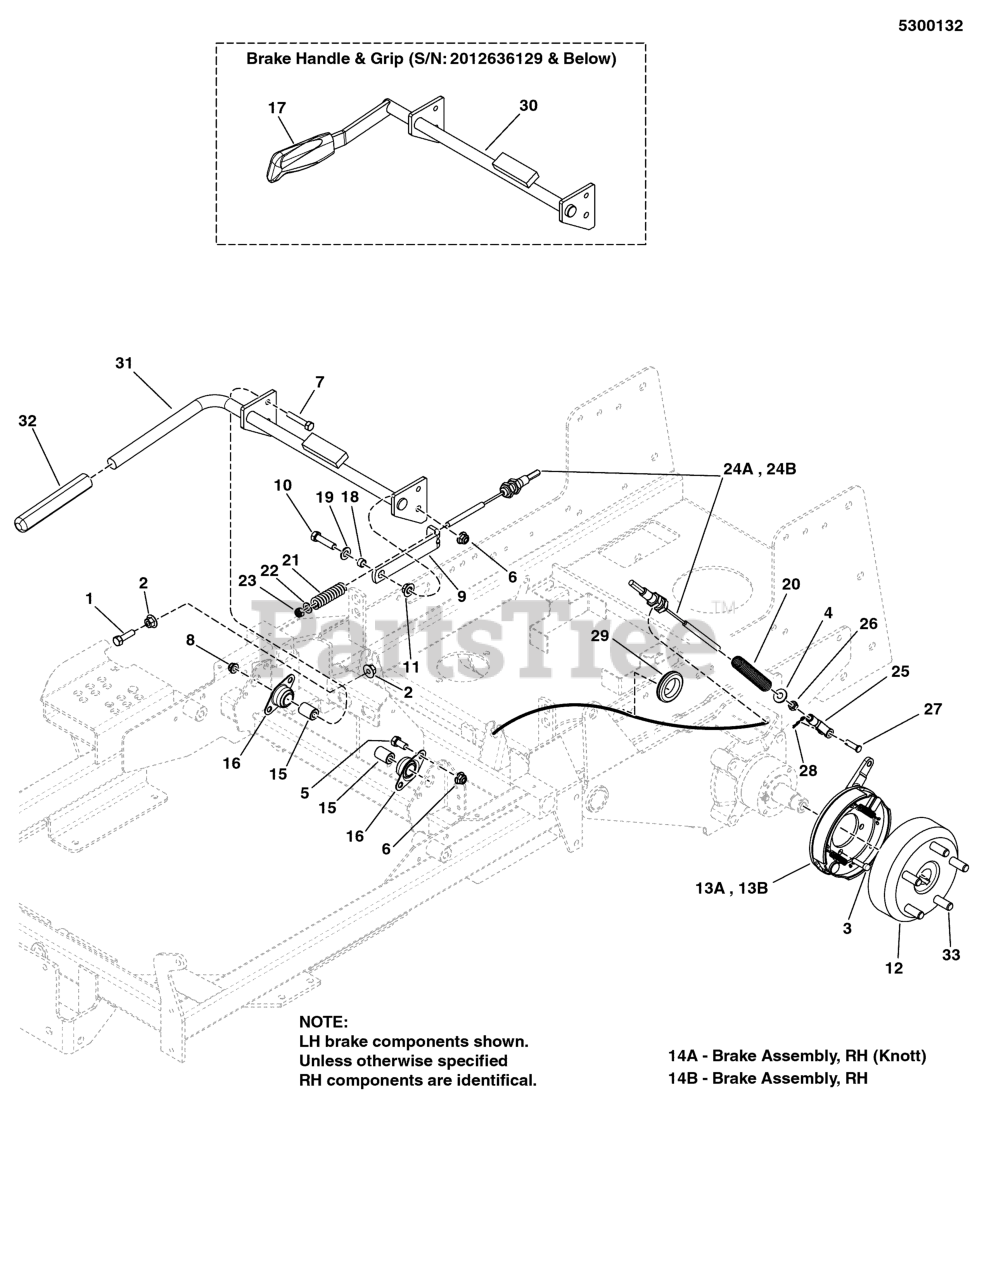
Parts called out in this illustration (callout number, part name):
1	BOLT, 5/16-18 X 1-1/8" GD5
2	NUT, 5/16-18 HEX SERRATED FLANGE (LARGE)
3	BOLT, 5/16-18 X 3/4 12PT FLANGE - PATCH
4	WASHER, 5/16" USS
5	BOLT, 3/8-16 X 3/4" GD5 CZ
6	NUT, 3/8-16 HEX NYLOCK FLANGE
7	BOLT, 5/16-18 X 1-3/4" GD5 YZ
8	NUT, 5/16-18 HEX NYLOCK FLANGE
9	LINK, BRAKE STOP, 6.0 - BLK
10	BOLT, 3/8-16 X 1-1/2" GD5 CZ
11	NUT, 3/8-16 HEX SERRATED FLANGE
12	BRAKE DRUM, 6", 5 BOLT, KNOTT
15	SPACER, .32 X .75 X 1.06
16	BEARING, BRONZE FLANGE, 3/4
17	GRIP, BLACK FLEXIBLE
18	SPACER, .38 X .50 X .27
19	WASHER, 3/8 SAE
20	SPRING, COMPRESSION
21	SPRING, BRAKE
22	WASHER, 5/16" SAE
23	NUT, 5/16-24 HEX NYLON LOCK
25	CLEVIS, 5/16-24, STEEL, CLEAR ZINC
26	NUT, 5/16-24 HEX
27	PIN, CLEVIS, 5/16" X 1
28	PIN, HAIR, .0585" X 1-1/8"
29	GROMMET, 1-1/4
30	WELD, BRAKE SHAFT
31	WELD, BRAKE SHAFT - BLK
32	GRIP, FOAM, 3/4 ID X 6 X .187
33	STUD, BRAKE HUB
